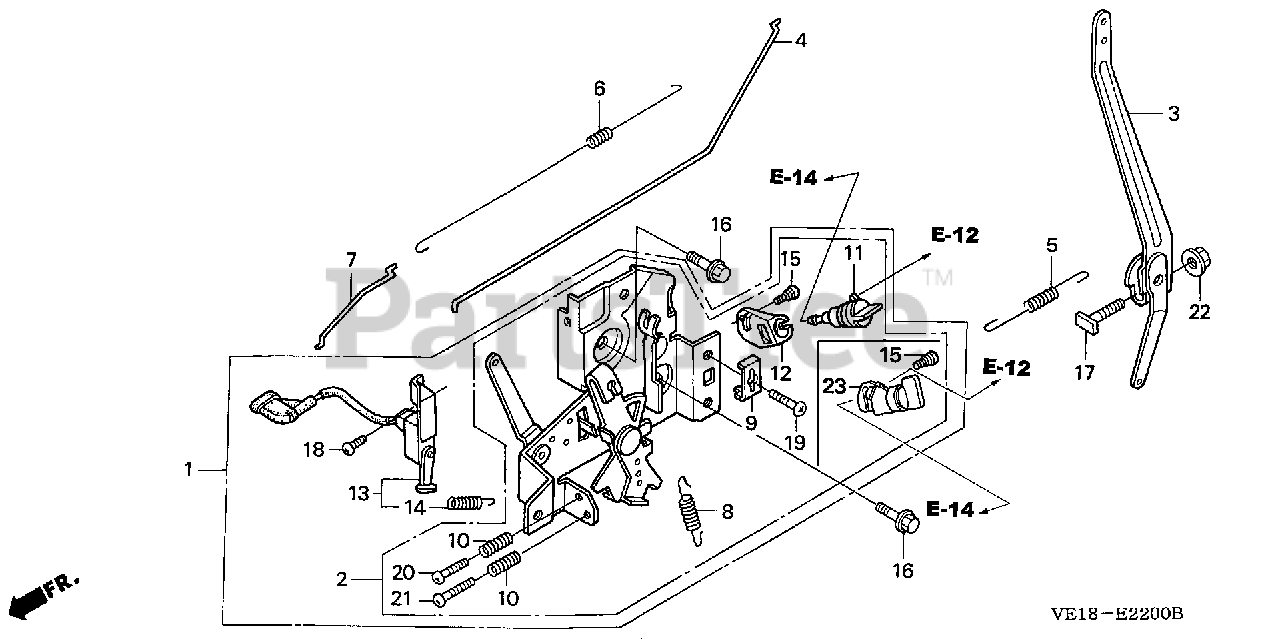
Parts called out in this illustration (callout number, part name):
1	CONTROL ASSY.
1	CONTROL ASSY. (NOT AVAILABLE)
3	ARM, GOVERNOR
4	ROD, GOVERNOR
5	SPRING, GOVERNOR
6	SPRING, THROTTLE RETURN
7	ROD, CHOKE
8	SPRING, LEVER
9	HOLDER, CABLE
10	SPRING, CONTROL ADJUSTING
11	PETCOCK ASSY.
12	BRACKET, PETCOCK
13	SWITCH ASSY., ENGINE STOP
14	SPRING, SWITCH CONTROL
15	SCREW, SHOULDER (5X12)
16	BOLT, FLANGE (6X14) (CT200)
17	BOLT, GOVERNOR ARM
18	SCREW, PAN (4X8)
19	SCREW, PAN (5X16)
20	SCREW, PAN (5X20)
21	SCREW, PAN (5X25)
22	NUT, FLANGE (6MM)
23	PETCOCK ASSY.
